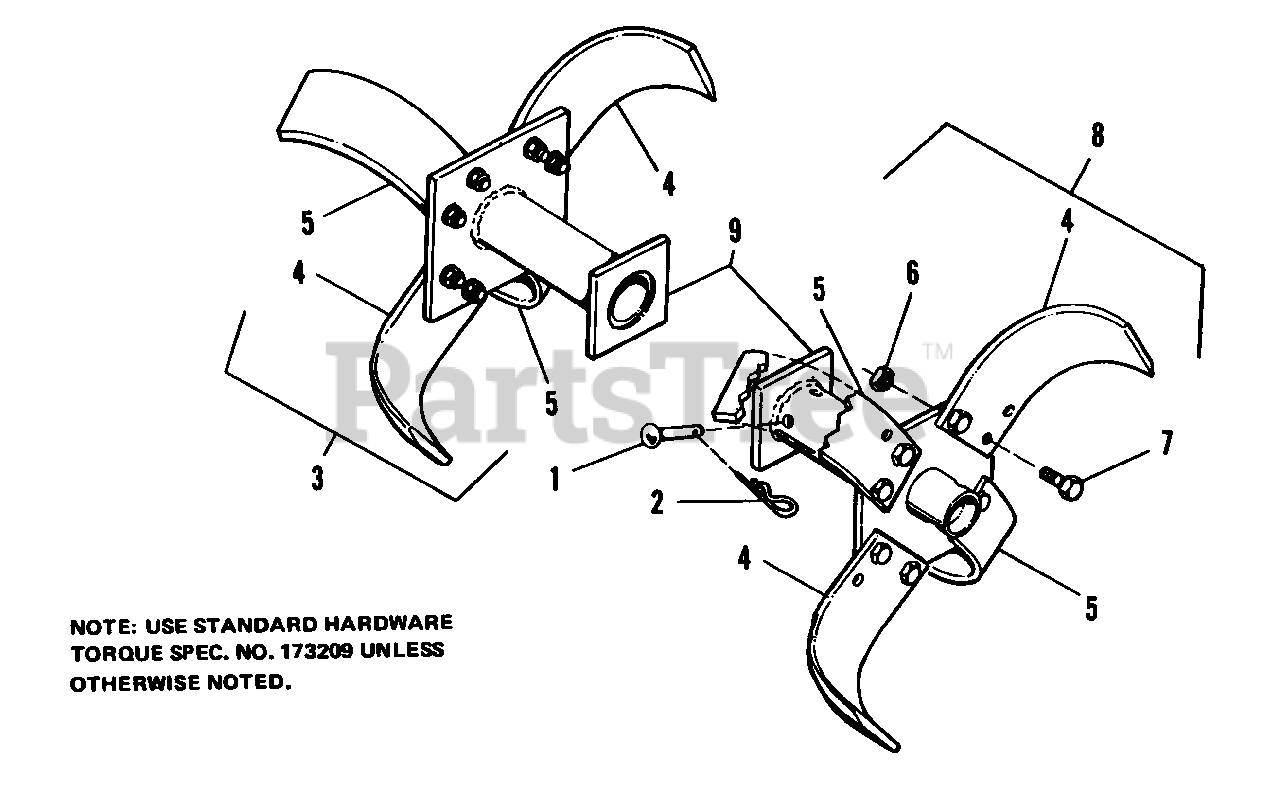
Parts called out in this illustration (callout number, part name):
1	PIN
2	PIN, Quick, 1-7/8
3	BLADE ASSY, L.H., Tine Ext.
4	TINE BLADE, R.H.
5	TINE BLADE, L.H.
6	NUT, Hex, Full Lock, 3/8-16
7	CAPSCREW, Hex Hd., 3/8-16 x 1
8	BLADE ASSY, R.H., Tine Ext.
9	PLATE ASSY, Tine Outer
